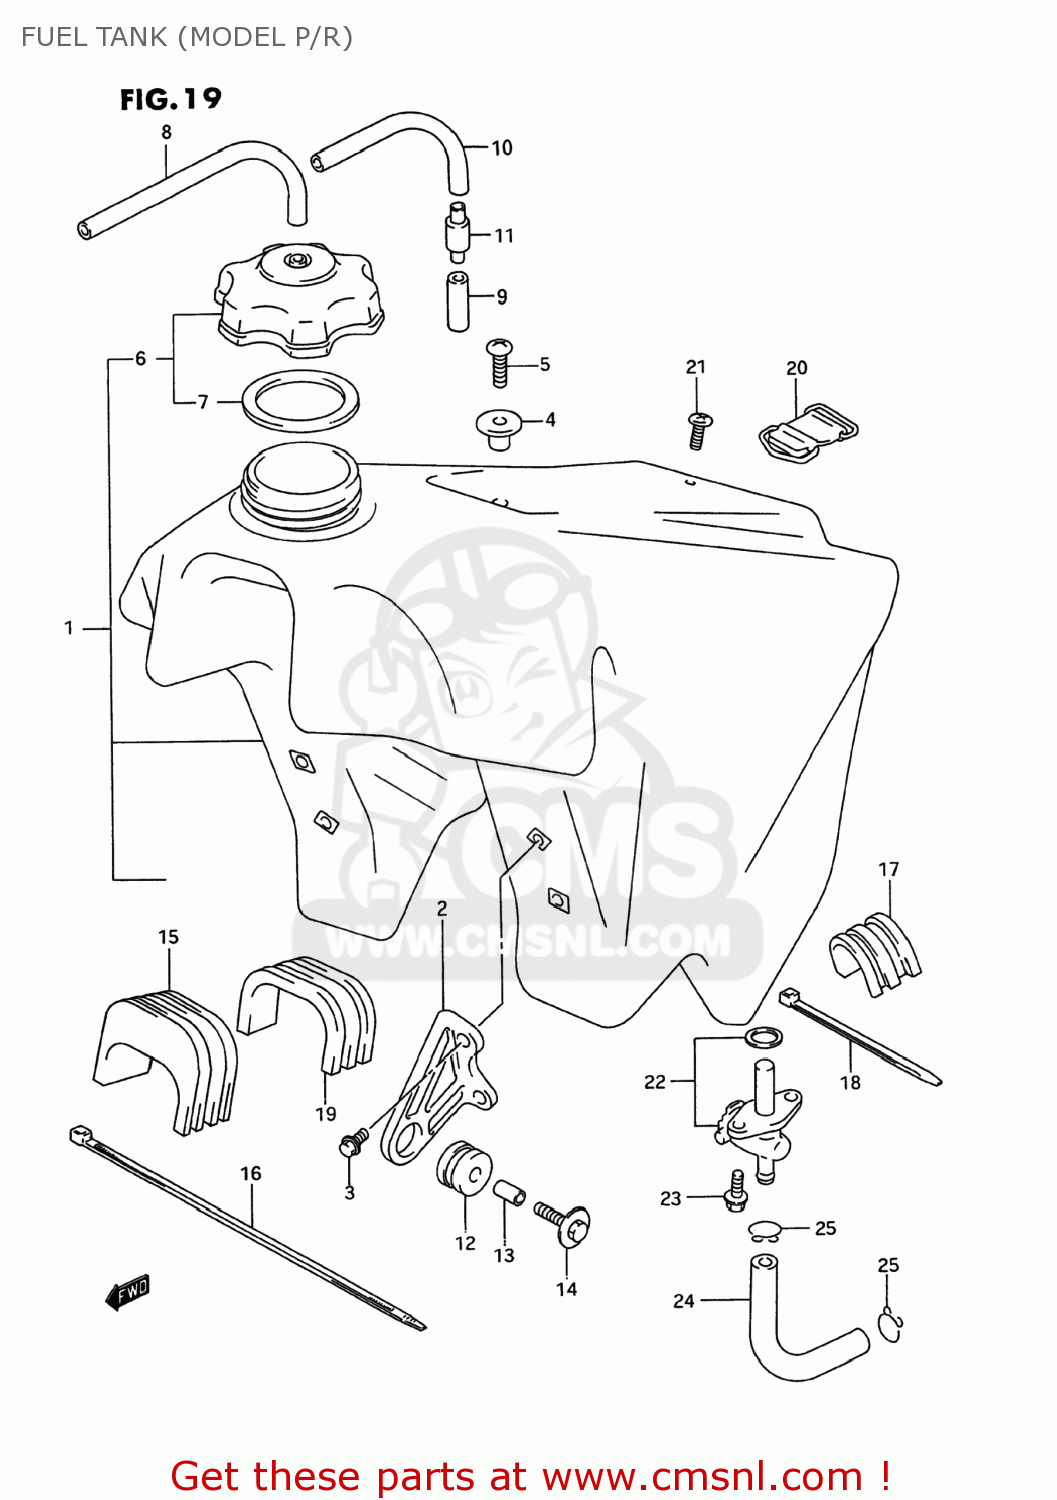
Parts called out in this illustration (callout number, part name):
1	TANK SET,FUEL
2	BRACKET,FUEL TANK,FRONT
3	BOLT
4	HOOK,SEAT FR
5	SCREW
6	CAP SET,FUEL TANK
7	GASKET,CAP (NAS)
8	HOSE
9	HOSE
10	HOSE
11	PLUG,FUEL TANK BREATHER
12	CUSHION,MUFFLER
13	SPACER (6.4X9X13.5)
14	BOLT(6X30)
15	CUSHION,FUEL TANK
16	CLAMP(L:300)
17	CUSHION,FUEL TANK NO.2
18	CLAMP(L:145)
19	CUSHION,FUEL TANK
20	BAND,FUEL TANK RR
21	SCREW
22	COCK ASSEMBLY,FUEL
23	SCREW
24	HOSE (6.5X11.5X300)
25	CLIP
